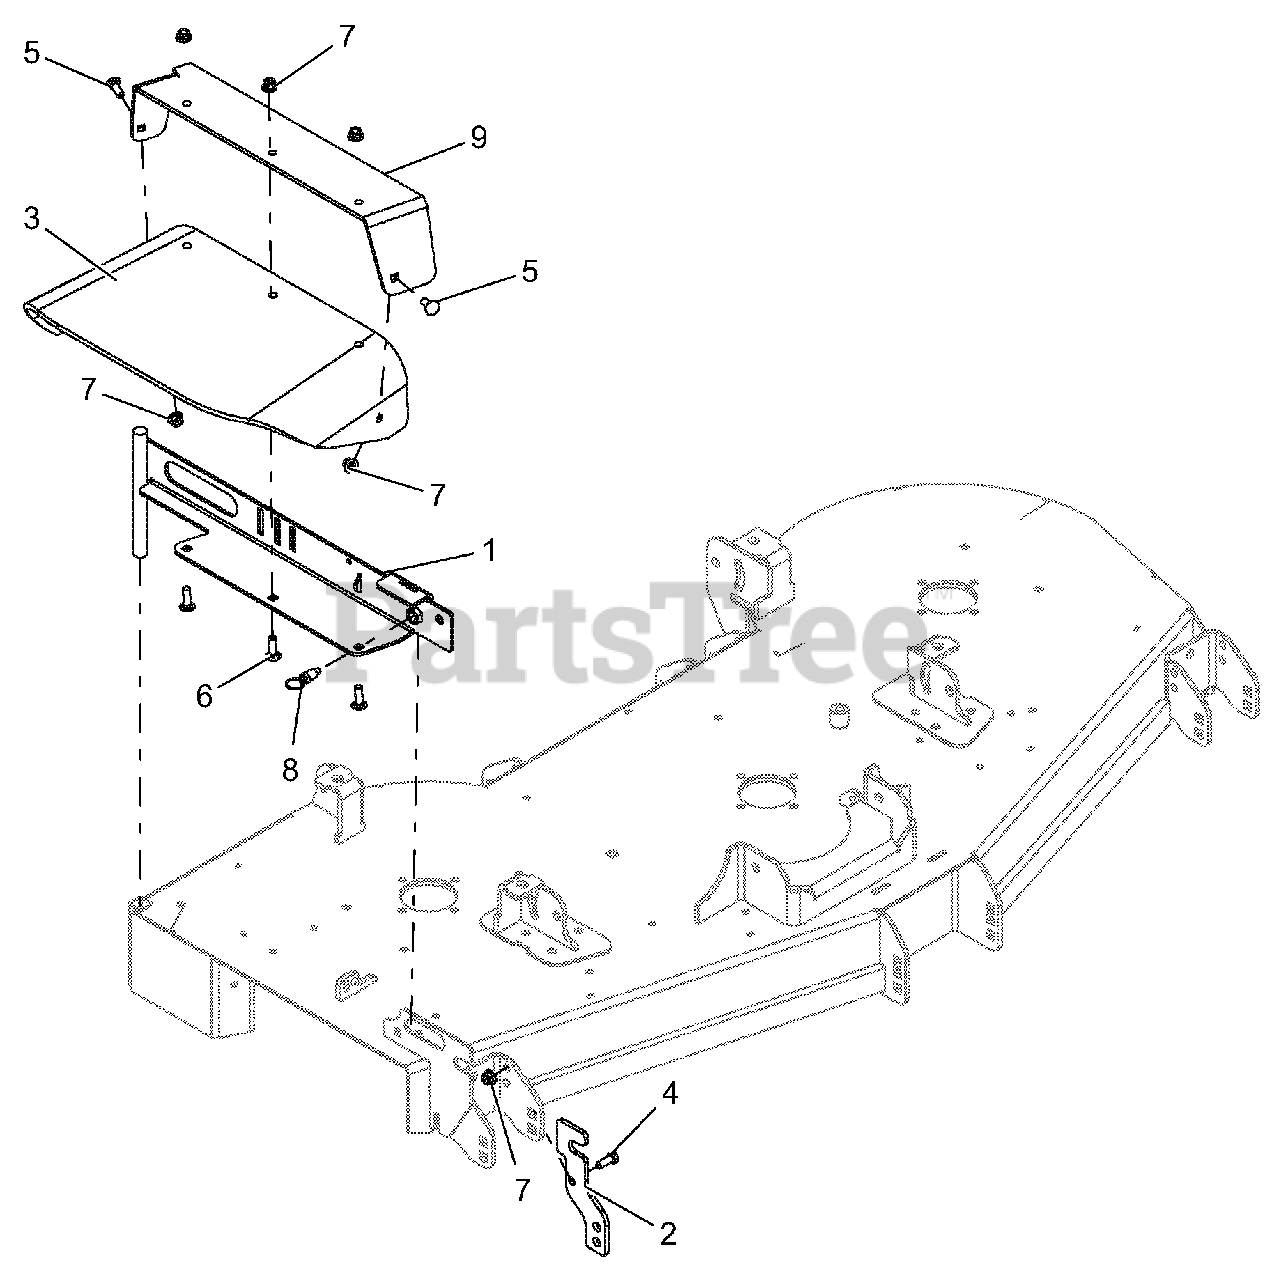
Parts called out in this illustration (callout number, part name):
1	WLDMT, 52"-60" DISCH CHUTE MTG-RED
2	CHUTE STORAGE BRACKET-RED
3	CHUTE, RUBBER DISCHARGE
4	BLT-HEX .38-16X1.00 GR5 YWZC
5	BLT-RDHDSQNK .38-16X1.00 G5 YWZC
6	BLT-RDHDSQNK .38-16X1.25 G5 YWZC
7	NUT-LK-NYL-FLG .38-16 YWZC
8	PULL PIN,.50-13THDX.310 PLNGR
9	DISCHARGE CHUTE SUPPORT W/SAFETY DECAL-RED
